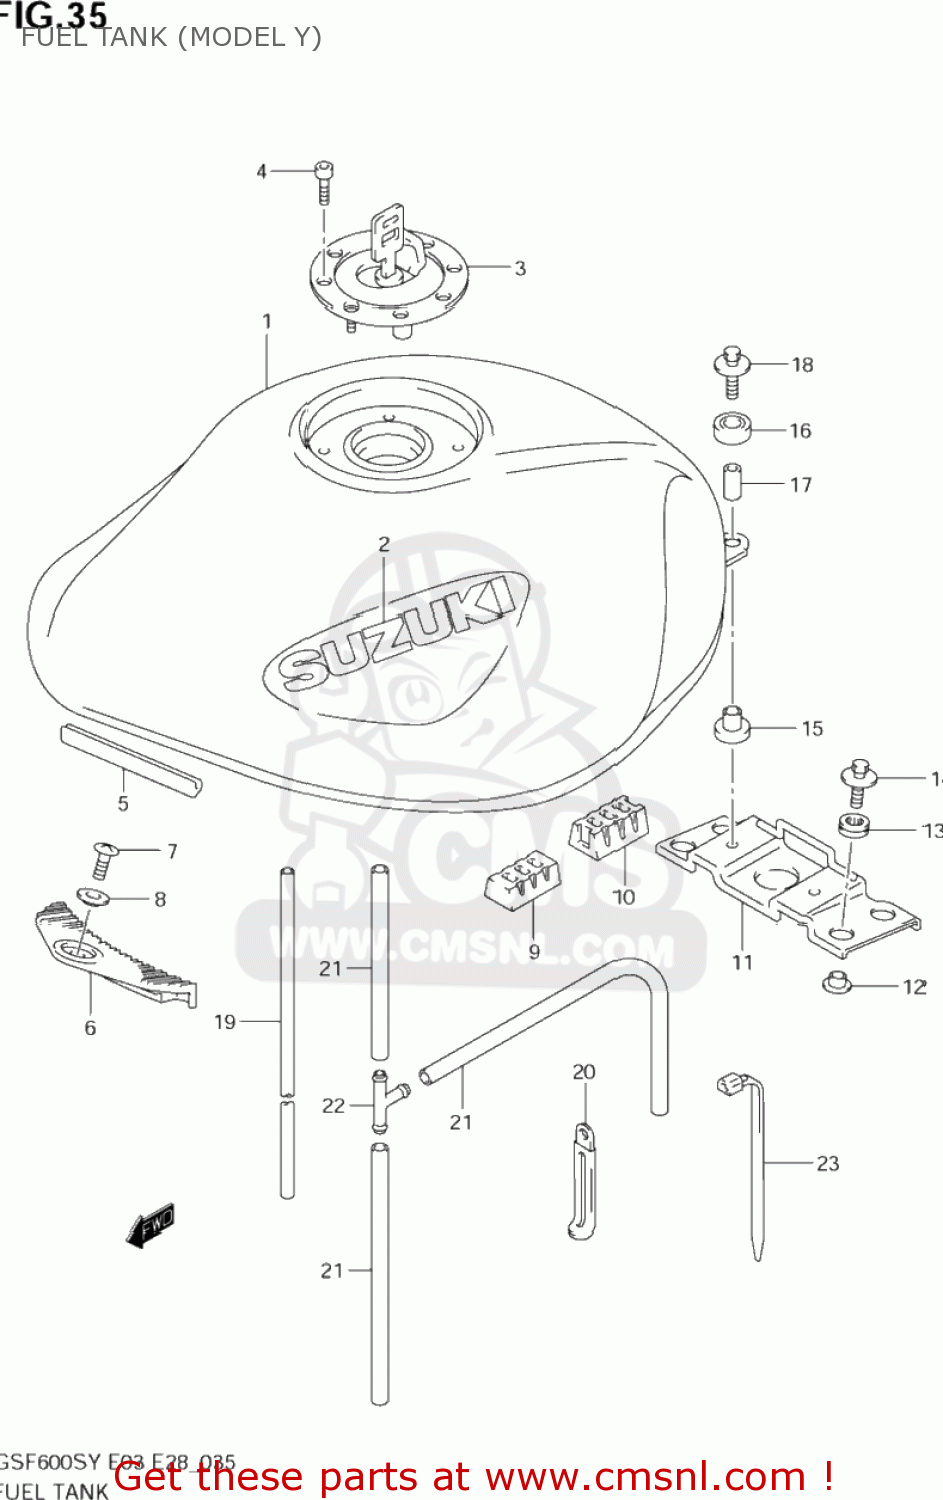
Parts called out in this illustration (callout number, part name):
1	TANK ASSY,FUEL(BLACK)
2	EMBLEM,FUEL TANK(GOLD)
3	CAP SET,FUEL TANK
4	BOLT(5X20)
5	MOLDING
6	CUSHION,FUEL TANK FR
7	SCREW
8	WASHER
9	CUSHION,SUPPORT(50X25X32)
10	CUSHION,TANK SIDE
11	BRACKET COMP,FUEL TANK
12	WASHER
13	CUSHION
14	BOLT(6X25)
15	CUSHION
16	CUSHION,FUEL TANK RR
17	SPACER(6.5X9X18)
18	BOLT(6X30)
19	HOSE(7X11X2000)
20	CLAMP(L:97)
21	HOSE(5X8.2X600)
22	JOINT,3 WAY
23	CLAMP(L:125)
